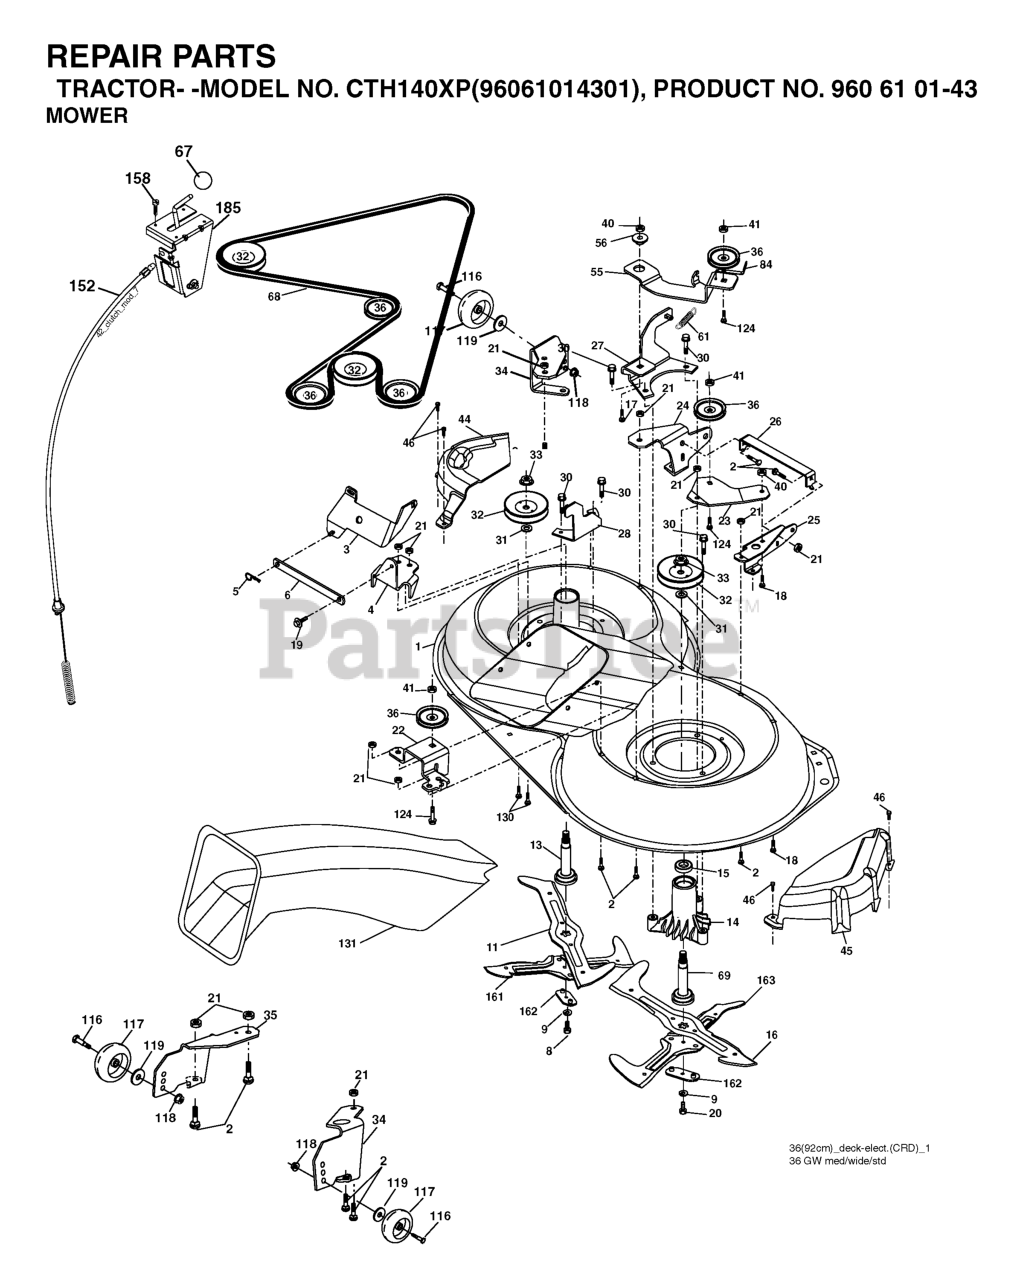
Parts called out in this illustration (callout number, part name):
2	RP BOLT 5/16-18 X3/4 ZN/YEL GR
5	RETAINER-SPRNG RB
6	BAR.SWAY.92.CRD
8	BOLT.3/8-24X1.25 GR8
9	LOCKWASHER
13	SHAFT ASM VENT
14	HOUSING.MANDREL.VENTED (MACHD)
17	BOLT.3/8-14X1.25
19	BOLT SHD 5/16-18
20	BOLT.3/8-24X1.25GR8. LHTHRD
21	LOCKNUT
26	SUPPORT
30	SCREW, WASHER HEAD
31	WASHER.SPACER.MANDREL
32	PULLEY, MANDREL
33	NUT.FLANGE.LOCK.TOP
36	PULLEY.IDLER.4.25
41	NUT LOCK FLG 3/8-16 UNC
45	COVER.MANDREL.RH.CRD
46	SCREW.1/4-20X5/8
55	ARM.IDLER.92 CRD.2006
56	SPACER.RETAINER.MOWER
61	SPRING.TENSION.BELT
67	KNOB T (3/8 HOLE)
68	BELT.DRIVE.92CM.CRD.2006
69	SHAFT.ASM.W/LWR.BRG.RH.THREAD
84	KEEPER, BELT IDLER
116	SHOULDER BOLT
117	RP WHEEL. GUAGE RALLY
118	LOCKNUT
119	WASHER.5/16.FLAT.STE.STD.
124	BOLT.3/8-16X1.50
130	BOLT.CARR.SQNK.5/16-18UNC.X3/4
131	CHUTE BAGGER
158	SCREW LT
185	HEAD ASM. CABLE CLUTCH
